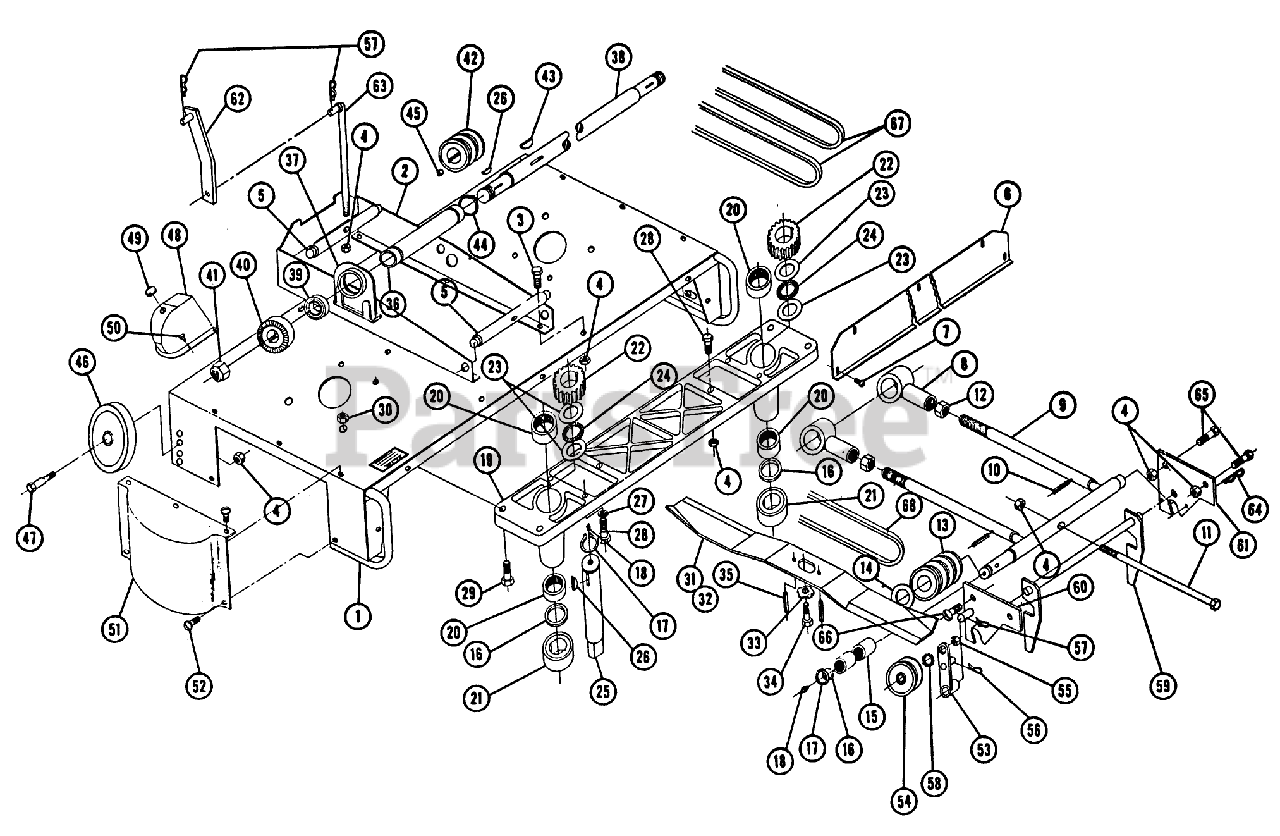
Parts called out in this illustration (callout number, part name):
3	Bolt 3/8-16 x 3/4
7	H.H.C.S. 1/4-20 x 1/2
10	ROLL PIN 1/8 X 1 1/2
11	Sq. Hd. Machine Bolt 3/8-16 x 8
12	Nut-5/8-18
14	WASHER
15	BEARING-NEEDLE
16	Seal
17	Snap Ring 3/4 I.D.
18	Zerk
20	NEEDLE BEARING
21	SPINDLE CUP
22	SPUR GEAR
23	WASHER-THRUST
24	Bearing Thrust
26	Key #5 Woodruff
27	Lockwasher
28	Bolt 3/8-16 x 1
29	Bolt 5/16-18 x 1
30	Nut-Nylok
31	Blade R.H. 18"
32	Blade L.H. 18"
33	WASHER
34	Bolt 3/8-16 x 7/8
35	SPIROL ROLL PIN
37	BEARING SUPPORT
38	SHAFT
39	Ball
40	Gear
41	Nut Hex 5/8-18 Thin
42	PULLEY
43	Key
45	Set Screw
46	Wheel
47	Bolt-Shoulder
48	COVER GEAR
49	PLUG BUTTON
50	SCREW
52	SCREW
54	IDLER PULLEY & SHAFT
55	Nut, 1/2-20
56	Hairpin
57	Hairpin
58	Lockwasher, 1/2 Ext.
59	Ass-y Latch & Shaft
60	Ass-y Plate Pin R.H.
61	PLATE-MTG BRKT LH R (NS)
62	Ring, Retaining
63	Rod
64	Hairpin
65	Bolt 3/8-16 x 1
67	V-BELTS - MATCHED PR
68	V Belt-28"
69	Decal
70	Decal-Caution
